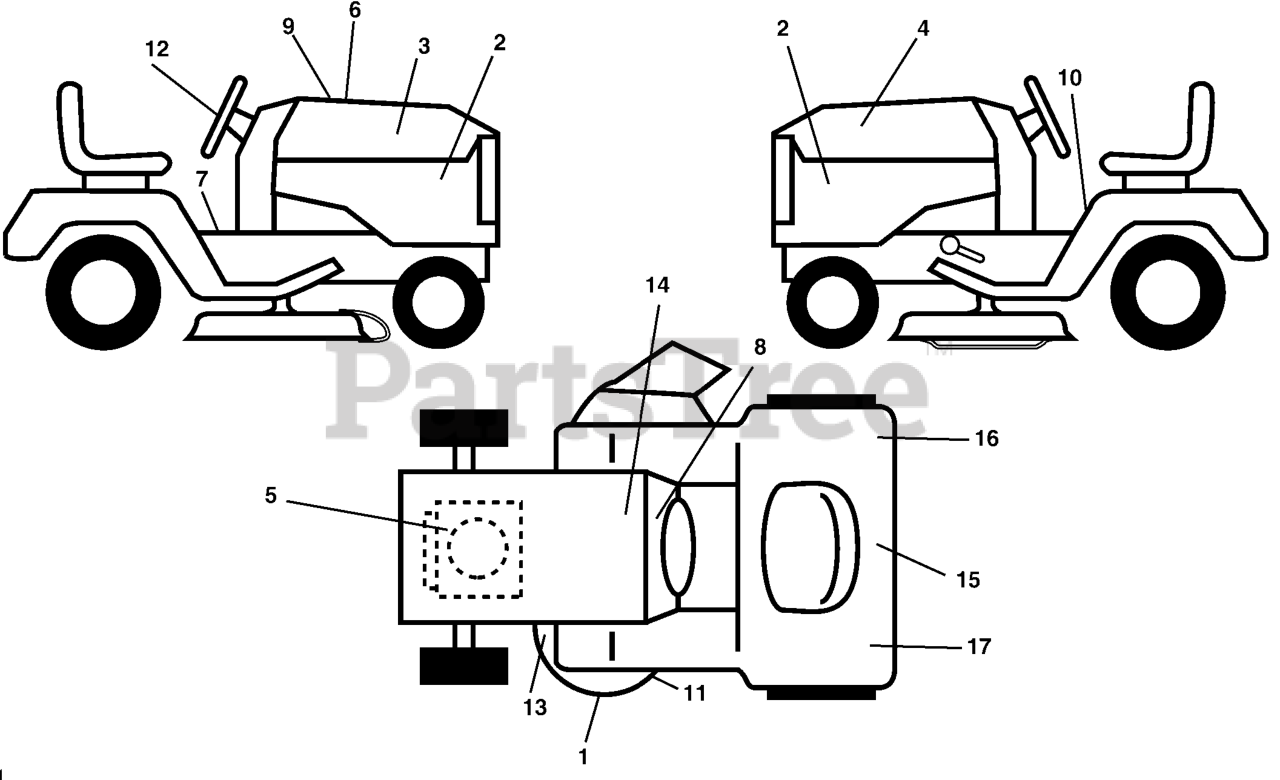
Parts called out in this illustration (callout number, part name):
1	DECAL, MOWER HEAVY DUTY
2	DECAL, PANEL YTH2448
3	DECAL, HOOD RH
4	DECAL, HOOD LH
5	DECAL.ENG.BS.24HP
6	DECAL HOOD CUST. RESP.
7	DECAL.FENDER.HYDRO.ENG
11	DECAL V-BELT SCHEMATIC
12	DECAL.STEERING.HUSQ.BLUE
13	DECAL.MOWER
14	DECAL BTRY SYMBOLS
15	DECAL.FENDER
16	DECAL RH REFLECTOR
17	DECAL REFLECTOR LH
